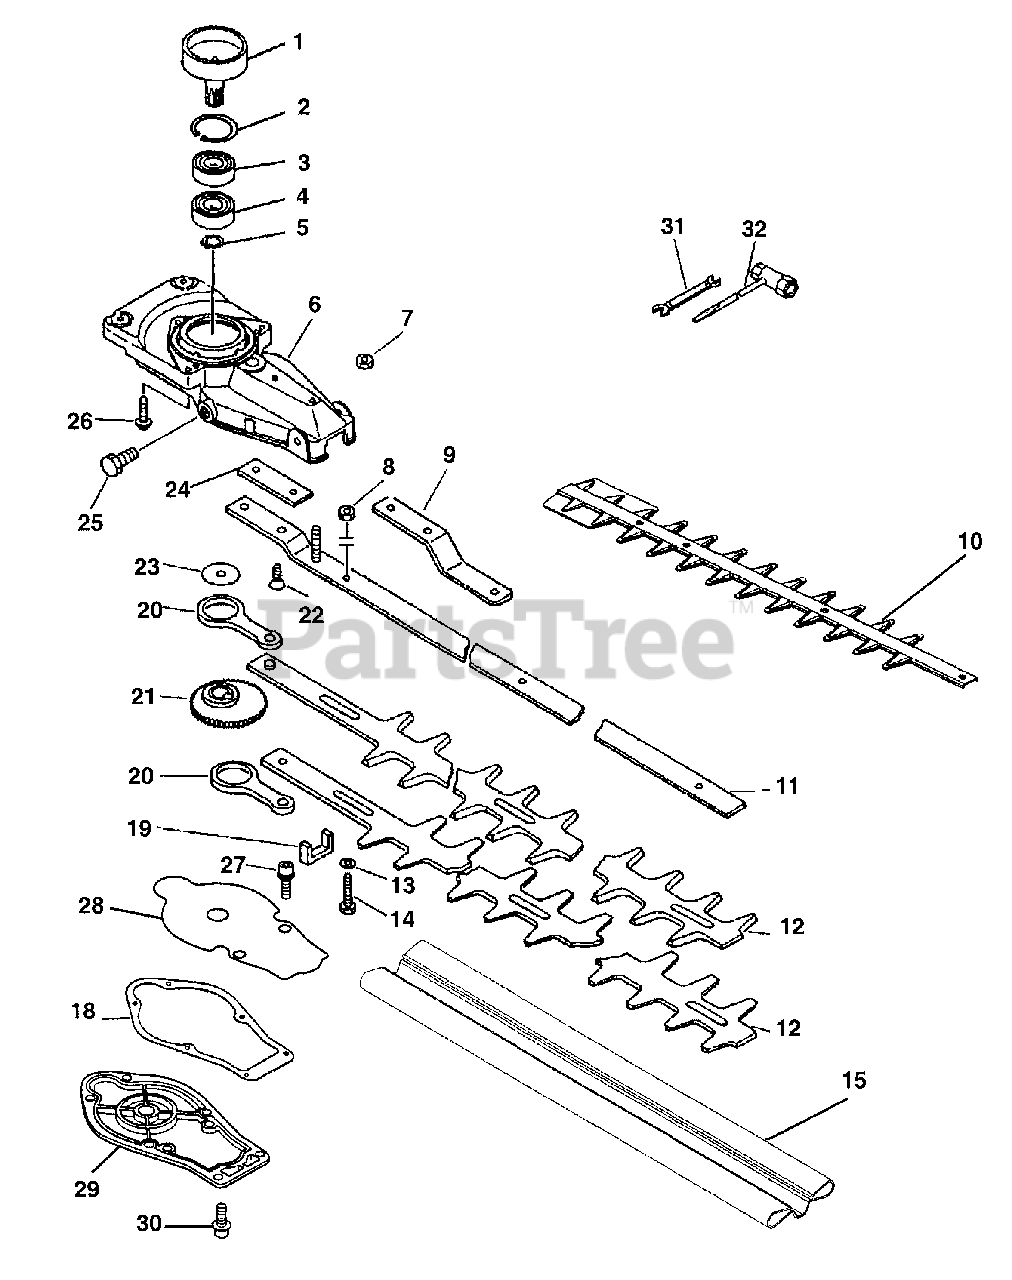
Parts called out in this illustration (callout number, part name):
1	DRUM, CLUTCH
2	RING, RETAINING - 35
3	BEARING, BALL - 6202
4	BEARING, BALL - 6202
5	RING, RETAINING - 14
6	CASE, GEAR - UPPER
7	LOCKNUT - 6
8	LOCKNUT - 6
9	PLATE, ANGLE
10	SUPPORT, BLADE
11	SUPPORT, BLADE
12	BLADE, TRIMMER
13	WASHER - 6
15	COVER, BLADE
18	GASKET, GEAR CASE
19	SEAL, FELT
20	ROD, CONNECTING
21	GEAR - DRIVE
22	SCREW - 6X25
25	BOLT - 8X8
26	SCREW - 5X25
27	SCREW - 5X12
28	LID, GEAR CASE
29	LID, GEAR CASE - LOWER
30	SCREW - 4X12
31	T-WRENCH - 13X19mm
32	SPANNER - 8X10mm
